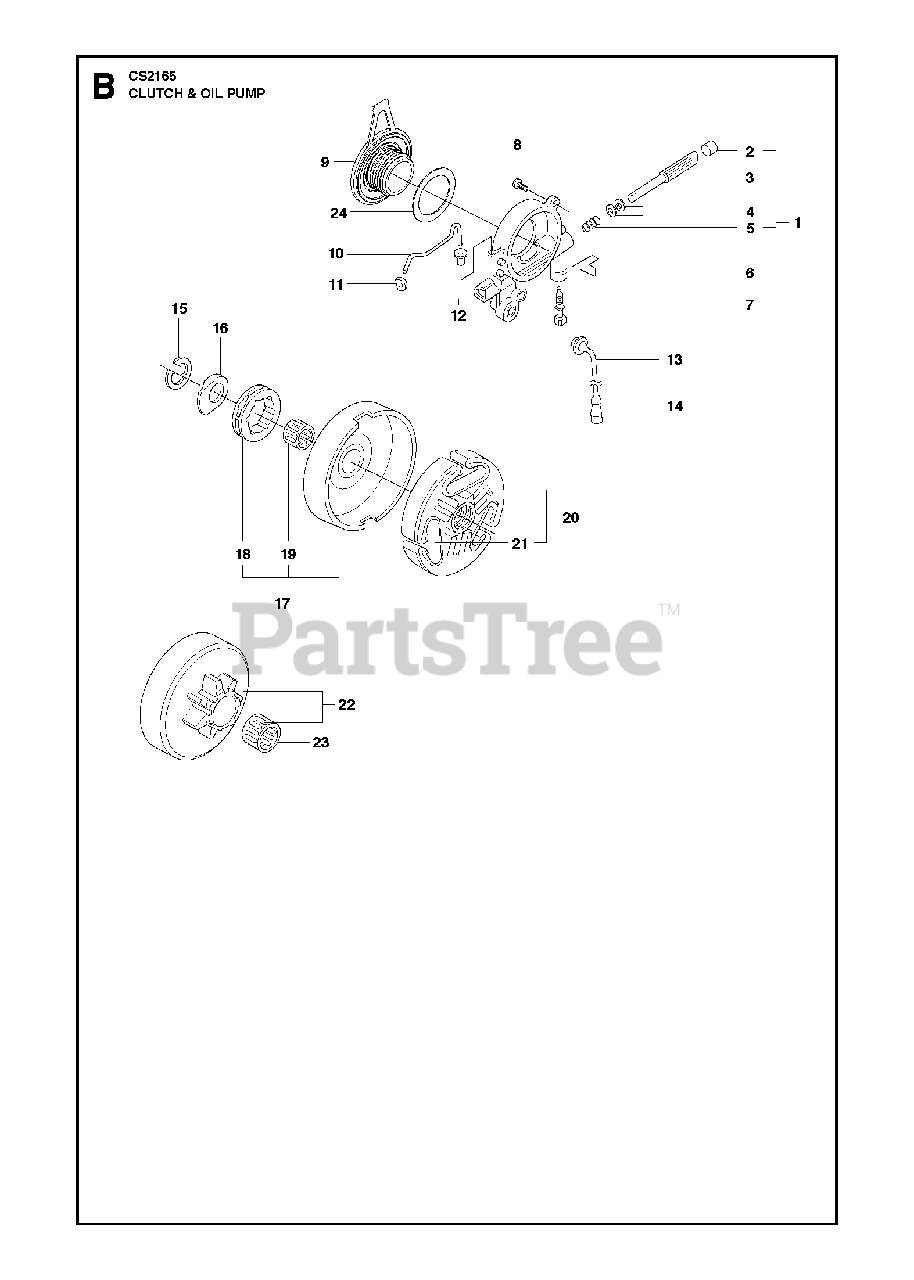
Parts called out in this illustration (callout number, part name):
1	OIL PUMP
2	PLUG
3	PUMP PISTON
4	WASHER 6.1X9
5	SPRING
6	SPRING CLIP
7	SCREW
8	SCREW MC6S 5X16
9	OIL PUMP DRIVE
14	OIL SCREEN
15	RETAINING RING
17	CLUTCH DRUM
18	68210 RIMSPROCKET
18	22273 SPROCKET
19	CLUTCH DRUM BEARING
20	CLUTCH
22	CLUTCH DRUM
23	CLUTCH DRUM BEARING
